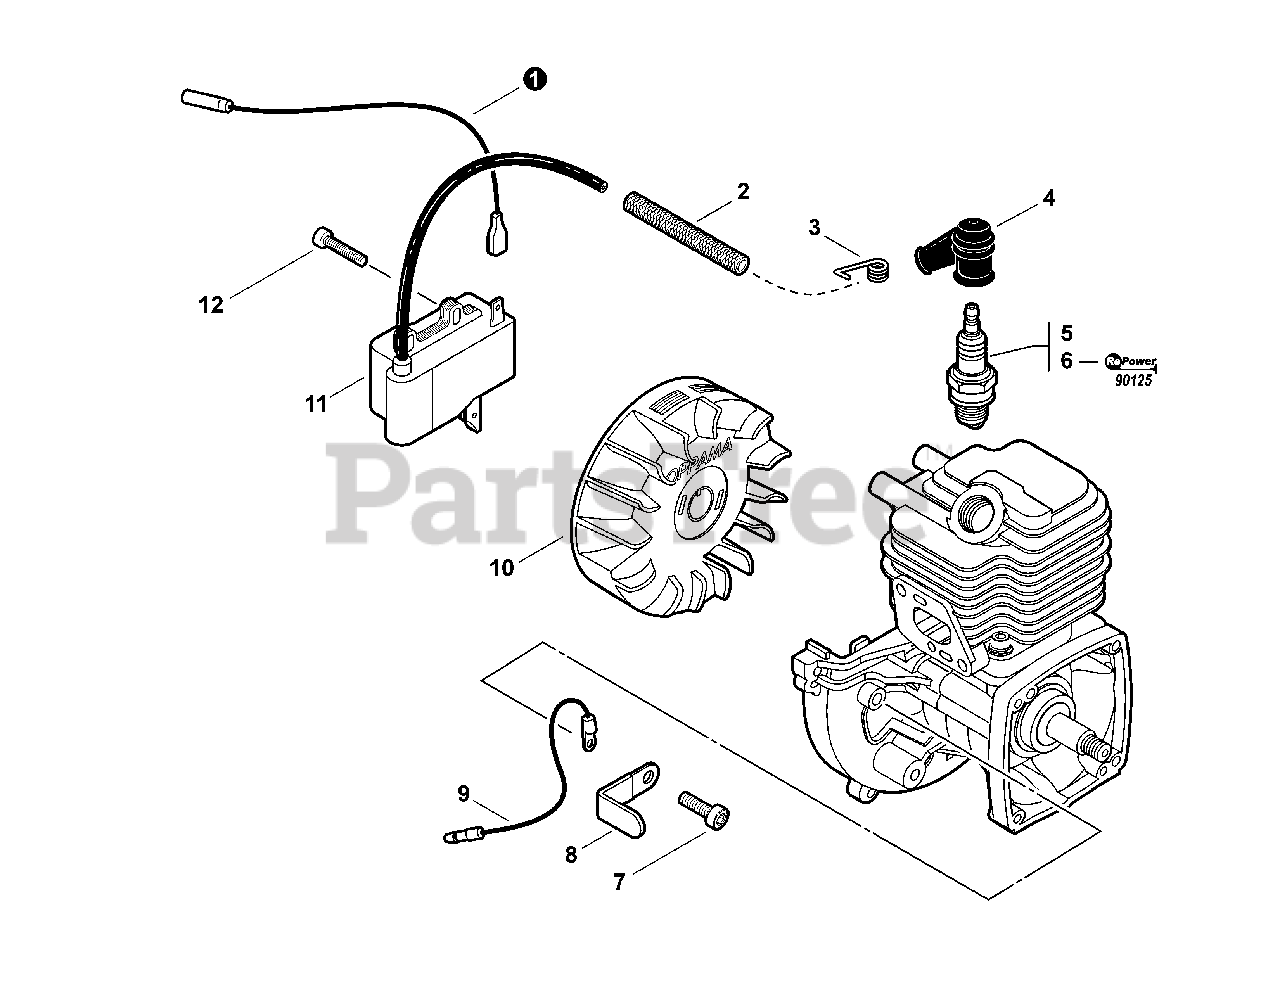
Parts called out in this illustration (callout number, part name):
1	LEAD - IGNITION
2	TUBE, INSULATOR
3	TERMINAL, SPARK PLUG CAP
4	CAP, SPARK
5	SPARK PLUG -- BPM-8Y
6	SPARK PLUG -- BPMR-8Y
7	SCREW - 5X10
9	LEAD - GROUND
10	FLYWHEEL
11	COIL, IGNITION
12	SCREW - 4X20 -- TORX
